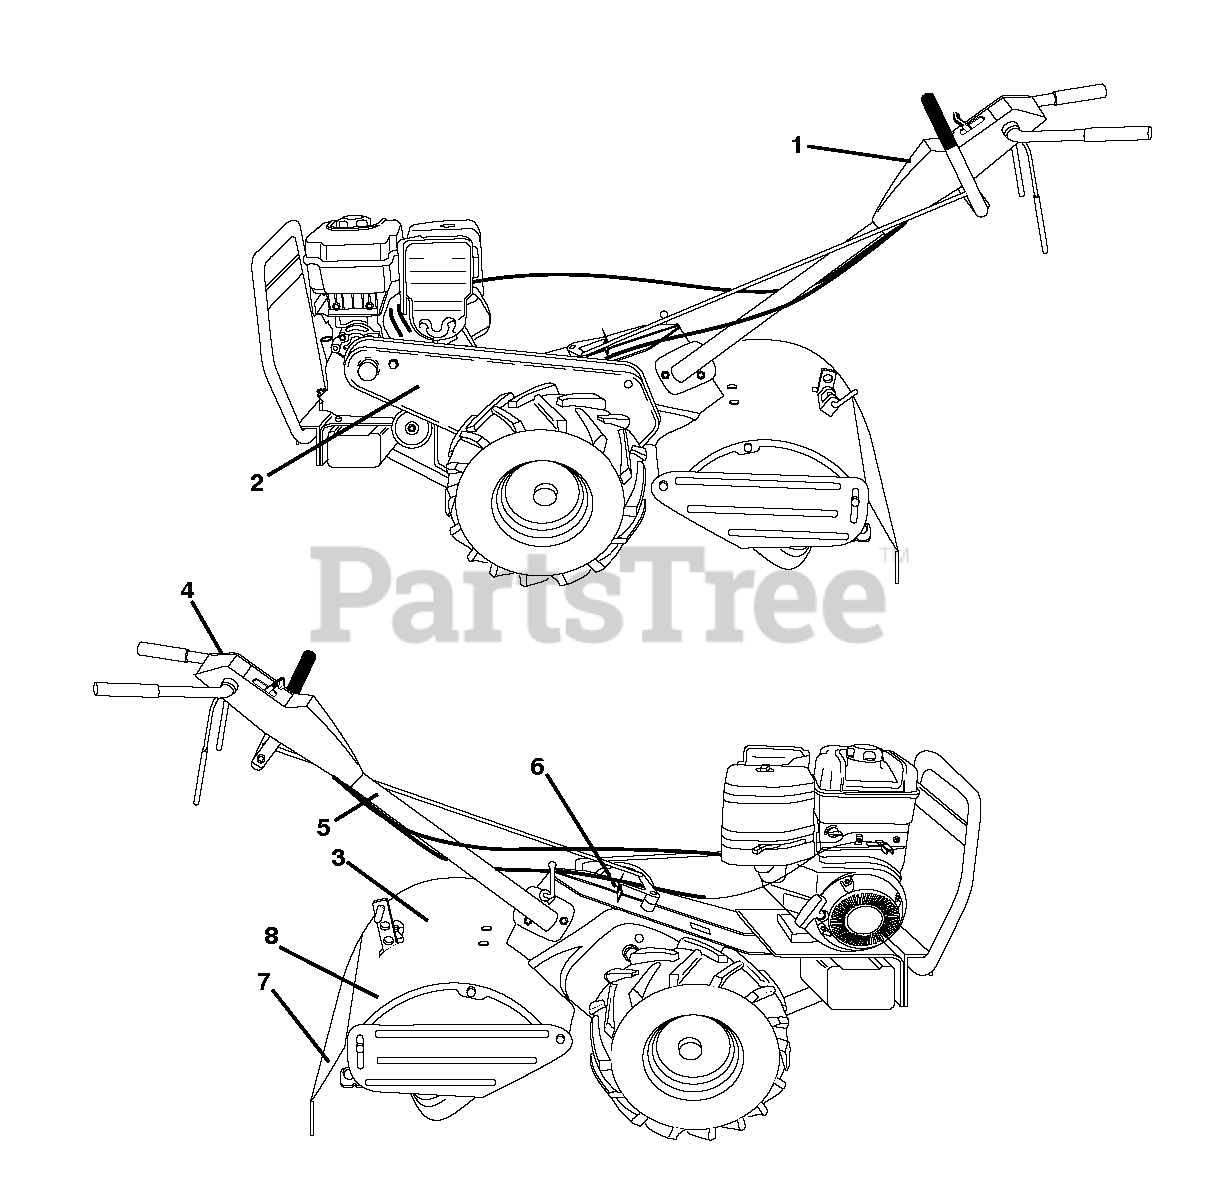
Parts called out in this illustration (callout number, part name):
2	DECAL.HOOD.LOGO.ORANGE.HUSQVAR
5	DECAL TI (2 2)
6	DECAL, SHIFT INDICATOR
7	DECAL TI
8	DECAL.WARNING.SHLD.ENG/FR
